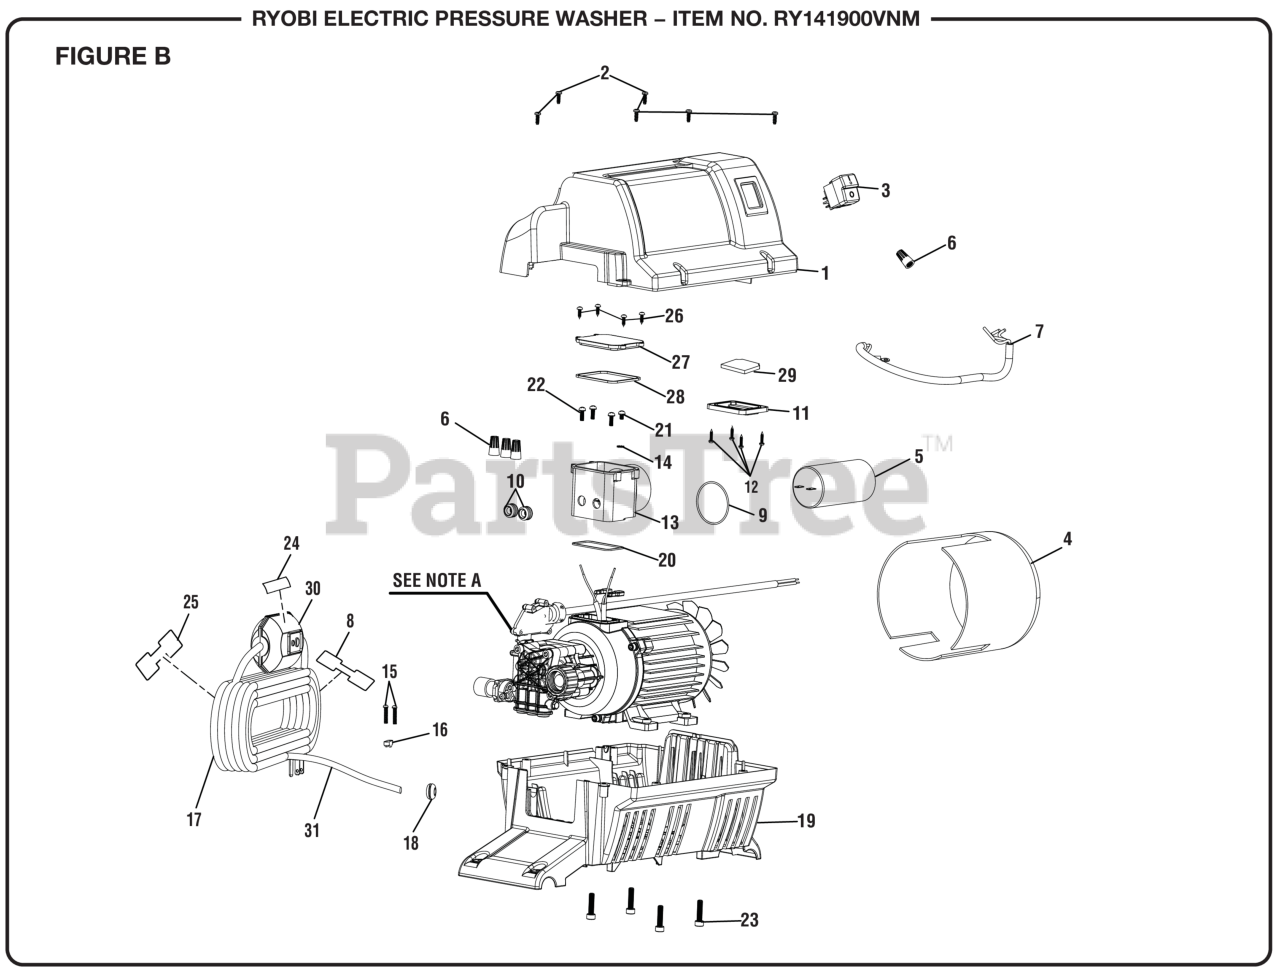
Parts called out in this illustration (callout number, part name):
1	Top Motor Housing
2	Screw (M4.2 x 15 mm, Phillips Hd. S.T.)
3	On/Off Switch
4	Nozzle (15deg)
5	Capacitor
6	Tuerca para alambre
7	Connecting Wire
8	Outlet Cord Wrap Label
9	O-ring (Capacitor)
10	Soap Tank Grommet
11	Switch Cover
12	Screw (M2.9 x 14 mm, Pan Hd.)
14	Toothed Lock Washer (M4)
15	Screw (M3.5 x 20 mm, Button Hd.)
16	Cord Clamp
17	Power Cord
18	Housing Rubber Grommet
19	Lower Motor Housing
20	Wire Box Gasket (Lower)
21	Screw (M4 x 16 mm, Pan Hd.)
22	Bolt (M4 x 12 mm, Pan Hd.)
23	Bolt (M6 x 20 mm, Hex Hd. Locking)
24	Power Cord Label
25	Cordwrap Warning Label
26	Screw (ST 3.5)
27	Wire Box Cover
28	Wire Box Gasket (Upper)
30	Electrical Plug
31	Electrical Cord
